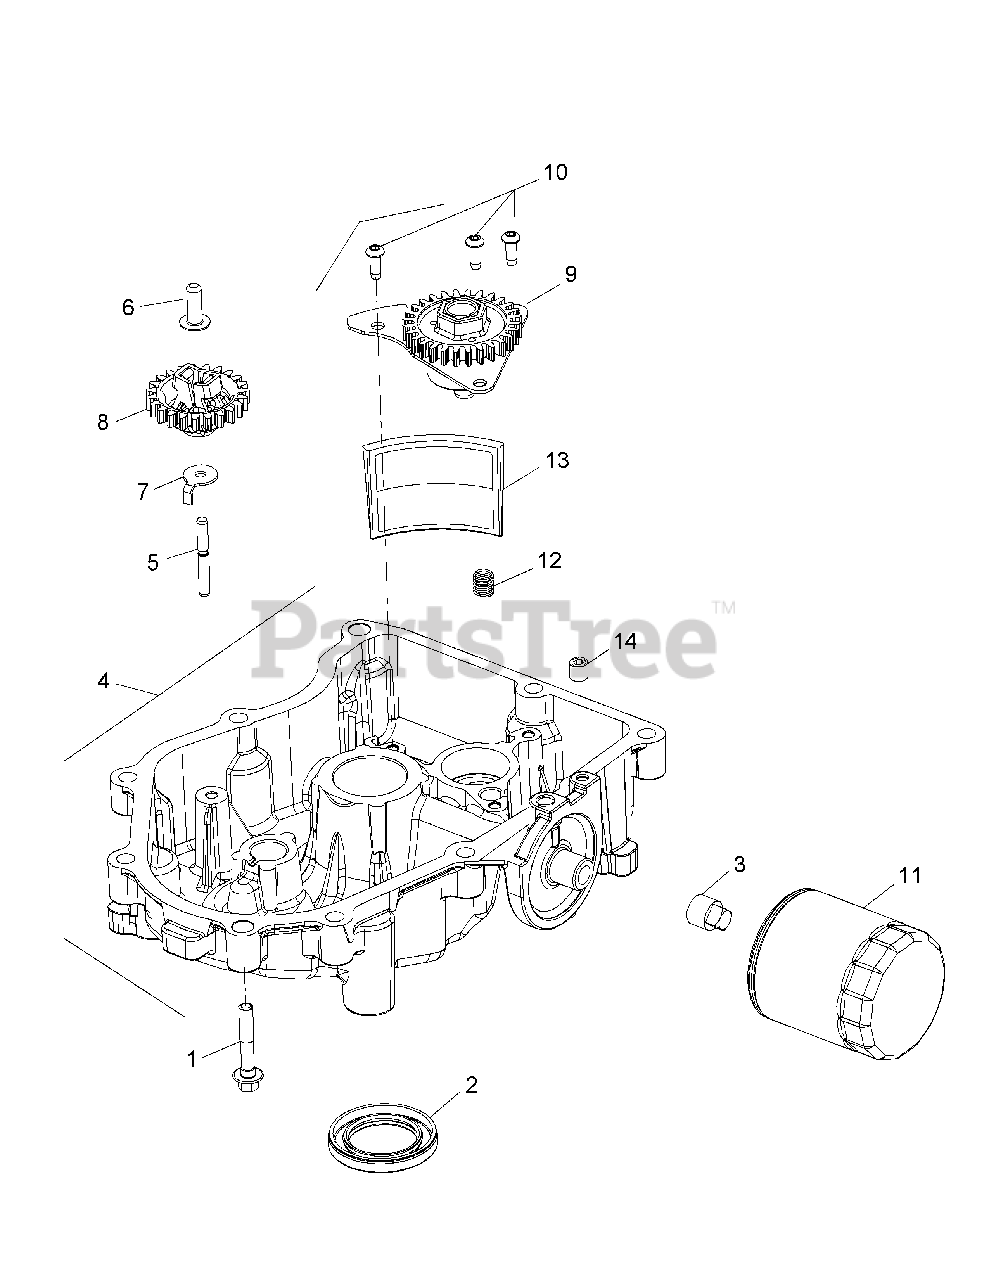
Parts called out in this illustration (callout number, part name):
1	Flange Screw, M8 x 1.25 x 45
2	Oil Seal, 2.38 x 1.45
3	Square Head Pipe Plug, 3/8
4	Oil Pan Assembly
5	Governor Gear Shaft
6	Governor Regulating Pin
8	Governor Gear Kit
9	Oil Pump Assembly
10	Button Head Screw
12	Compression Spring
14	Pipe Plug, 1/8
